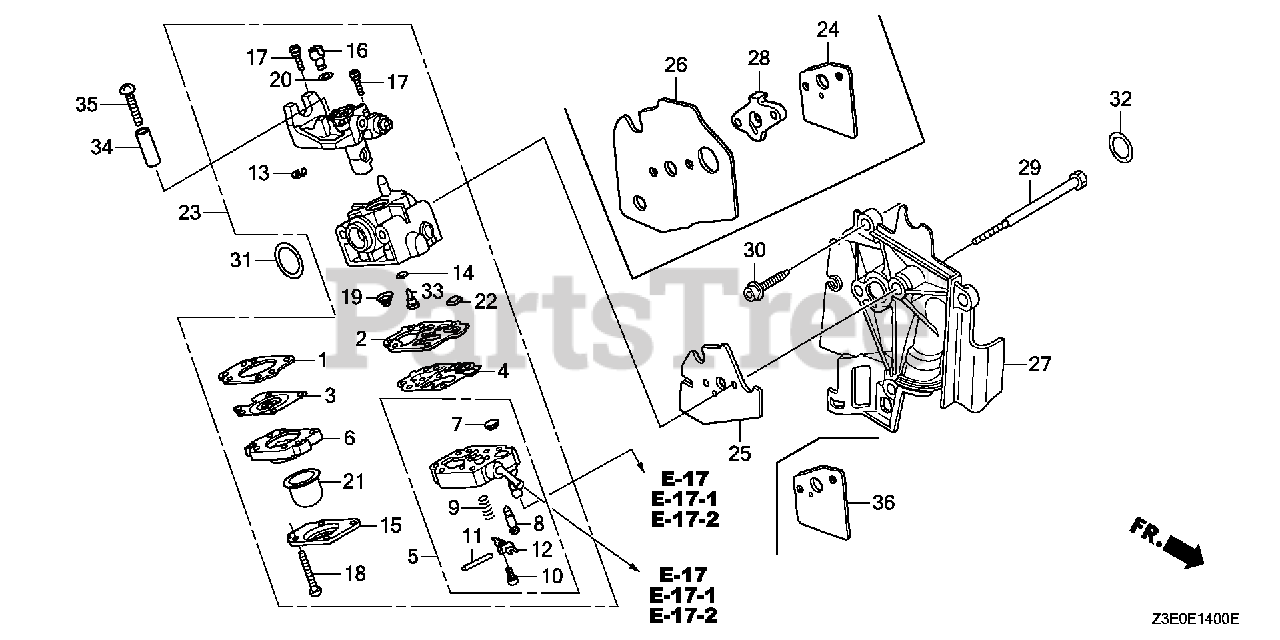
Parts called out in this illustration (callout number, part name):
1	GASKET, METERING DIAPHRAGM
2	GASKET, PUMP (CARBURETOR NO.)
3	DIAPHRAGM ASSY., METERING
4	DIAPHRAGM, PUMP
5	BODY ASSY., PUMP (CARBURETOR NO.)
6	BODY ASSY., AIR PURGE
7	SCREEN, INLET (CARBURETOR NO.)
8	VALVE, INLET NEEDLE
9	SPRING, METERING LEVER
10	SCREW, METERING LEVER PIN
11	PIN, METERING LEVER
12	LEVER, METERING
13	RING, RETAINING
15	COVER, PRIMER PUMP
17	SCREW, THROTTLE COLLAR
18	SCREW, PUMP COVER
19	SPRING, PUMP
21	PUMP, PRIMER
22	FILTER, FUEL INLET (CARBURETOR NO.)
23	CARBURETOR ASSY. (WYB 6F)
25	GASKET, CARBURETOR
27	SHROUD
29	BOLT (5X53)
30	BOLT, SOCKET (5X16)
31	O-RING (14.8X2.4)
32	O-RING (12.3X2.4) (CARBURETOR NO.)
33	JET (#33) (CARBURETOR NO.)
33	JET (#34) (CARBURETOR NO.)
33	JET (#32) (CARBURETOR NO.)
